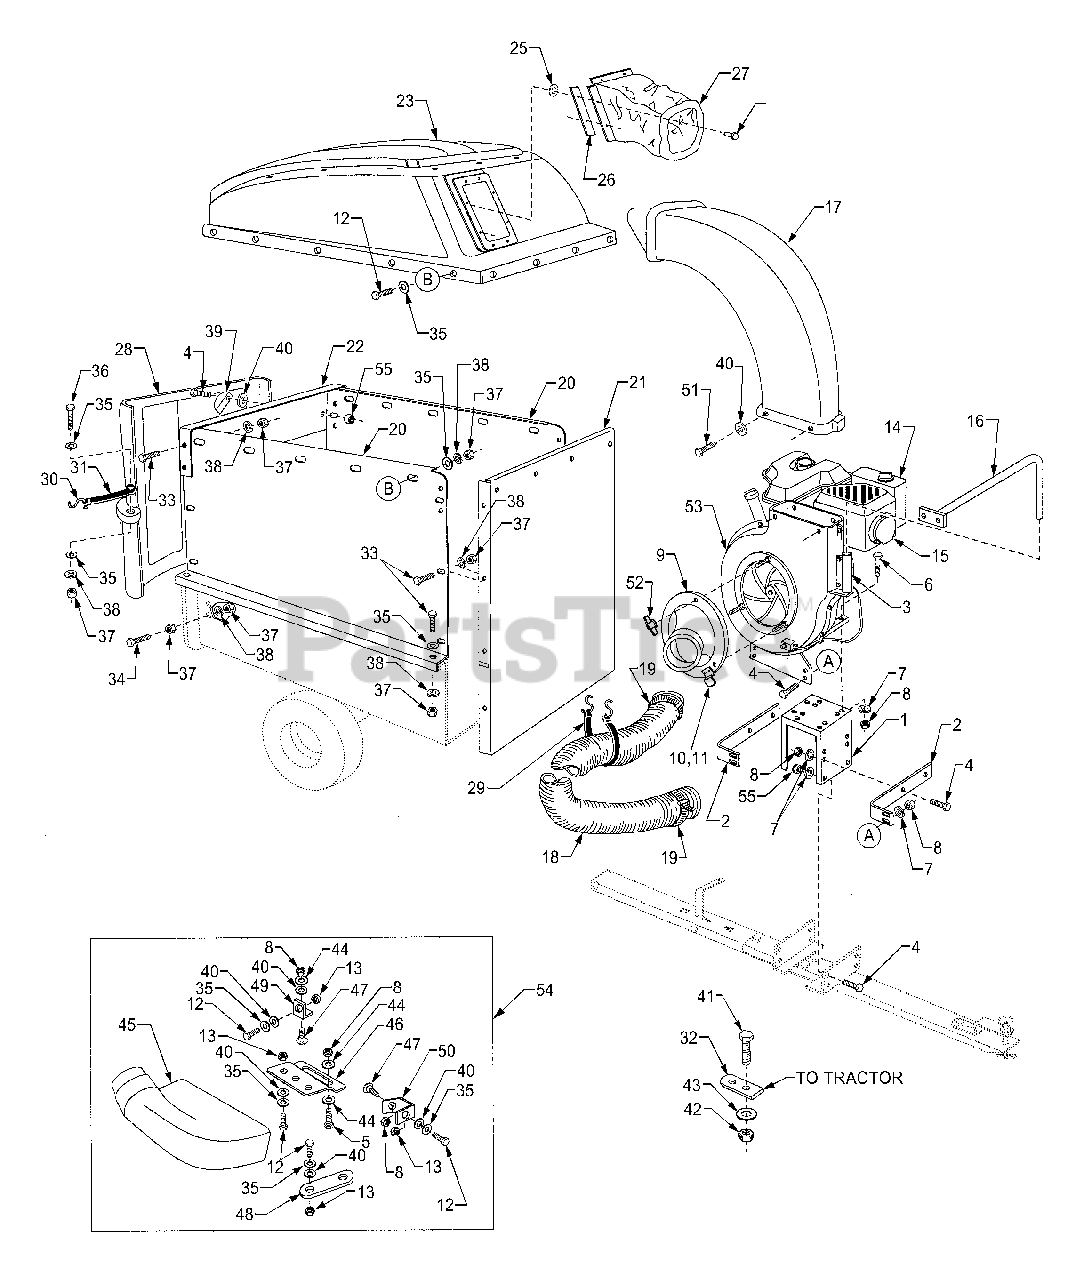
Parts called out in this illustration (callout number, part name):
1	Engine Base
2	Brace,Housing
3	Hose Hanger Bracket Ass'y.
4	Bolt,Hex 5/16-18 x 3/4"
5	Bolt,Hex 5/16-18 x 1"
6	Bolt,Hex 5/16-18 x 1-1/2"
7	Lockwasher,5/16"Spring Type
8	Nut,Hex Lock 5/16-18
9	Assembly,Hose Adapter
10	Bracket,Switch (Actuator)
11	Rivet,Pop 5/32"
12	Bolt,Hex 1/4-20 x 3/4"
13	Nut,Hex Lock 1/4-20 Thd.
15	Deflector,Muffler
16	Hose Hanger Rod Ass'y.
18	Hose (6"x 84")
19	Hose Clamp 6"
23	Hard Top Assembly
25	Washer,Flat 3/16"
26	Boot Mounting Strap
27	Hard top Boot
28	Poly Rear Door
29	Strap,Tarp 25"
31	Strap,Tarp (Less Hooks)
32	Hitch Plate
33	Bolt,Hex 1/4-20 x 5/8"
34	Bolt,Hex 1/4-20 x 1"
35	Washer,1/4"STD
36	Bolt,Hex 1/4-20 x 1-1/4"
37	Nut,Hex 1/4-20
38	Lockwasher,Spring 1/4"
39	Door Latch
40	Washer,Nylon 21/64"
41	Bolt,Hex 1/2-13 x 1-1/4"
42	Nut,Hex Lock 1/2-13
43	Washer,Flat 7/16"
44	Washer,5/16"STD
45	Adapter,Deck
46	Bracket,Deck Adapter
47	Bolt,Carr.5/16"x 3/4"
48	Mounting Strap
49	Angle Bracket
50	Mounting Bracket
51	Screw,Self Tap 5/16-18 x 3/4"
53	Impeller Housing Assembly
54	Deck Adapter Kit
55	Nut,Nylock 5/16-18
